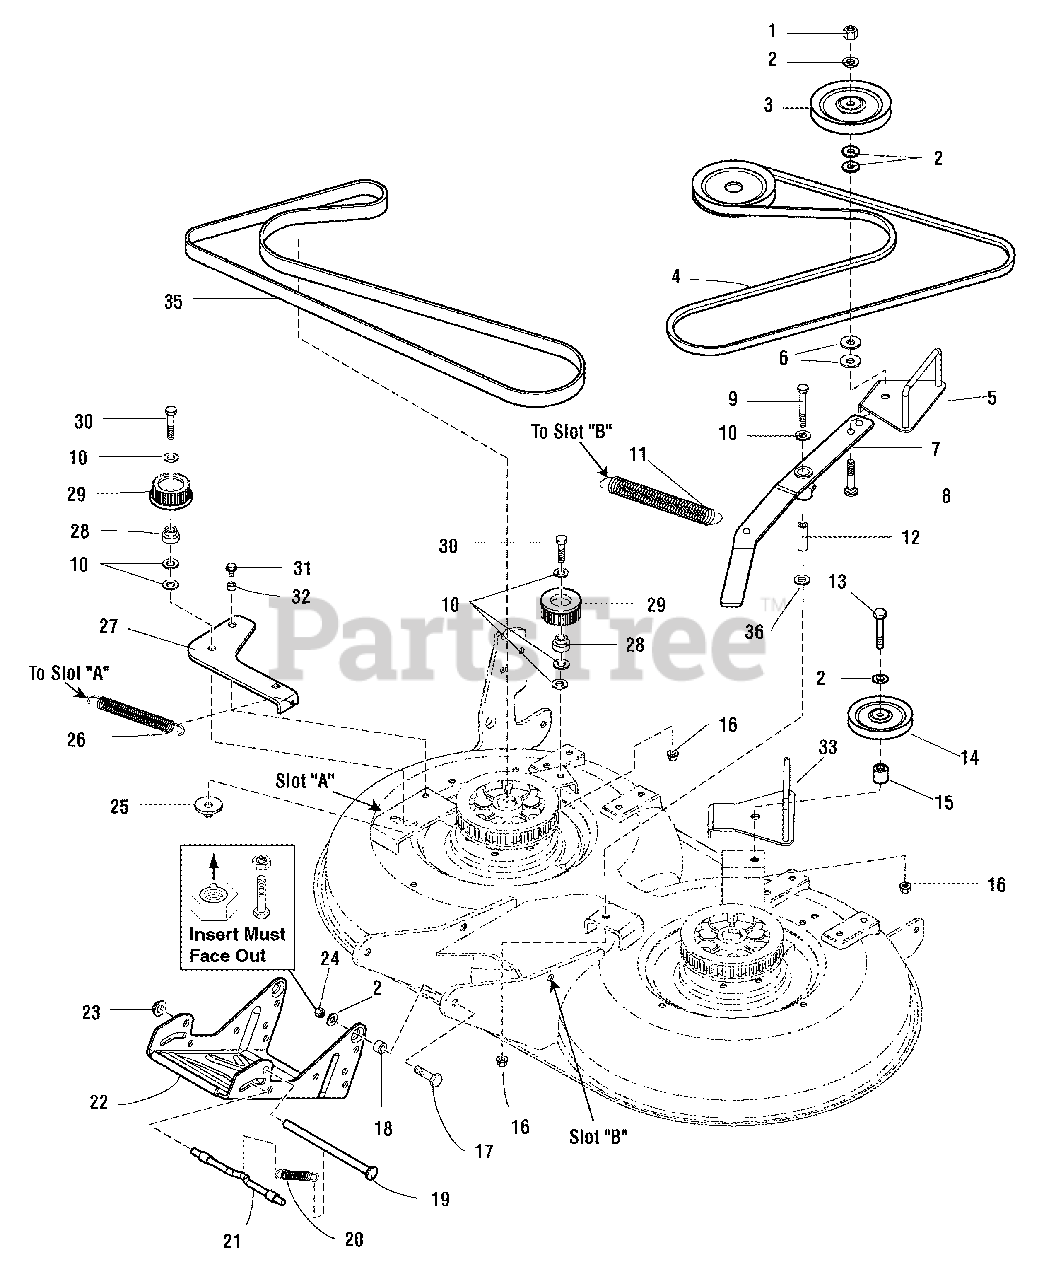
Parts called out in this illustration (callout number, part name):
1	NUT, Hex Lock Esna Light, 3/8-16
2	WASHER, 3/8
3	PULLEY, Idler
4	V-BELT, Arbor Drive
5	BELT GUIDE
6	WASHER, 3/8
7	ARM ASSEMBLY, Idler with Bushings & Fitting, 38 Tooth
8	CARRIAGE BOLT, 3/8-16 x 2
9	CAPSCREW, Hex Head, 3/8-16 x 2-3/4 G8
10	WASHER, 3/8
11	SPRING, Extension, Idler Arm
12	SPACER, Hardened
13	CAPSCREW, Hex Head, 3/8-16 x 2-1/4
14	PULLEY
15	SPACER
16	NUT, Hex Flange Whiz Lock, Large, 3/8-16
17	CAPSCREW, Hex Head, 3/8-16 x 1-3/8
18	SPACER
19	ROD, Mower Hitch
20	SPRING, Extension, Hitch Release
21	ROD, Latch
22	HITCH, Mower
23	NUT, Push
24	NUT, Hex Toplock Sprial Flange, 3/8-16
25	WASHER & NUT ASSEMBLY, 3/8 x 1-1/2
26	SPRING, Extension
27	ARM, Idler
28	HUB
29	PULLEY, Idler
30	SCREW-Hex Head Flange 3/8-16 x 2
31	CAPSCREW, Taptite Hex Washer Head, 5/16-18 x 1/2
32	SPACER
33	BELT GUIDE
35	BELT, Timing, 38 Tooth
36	WASHER, 3/8
